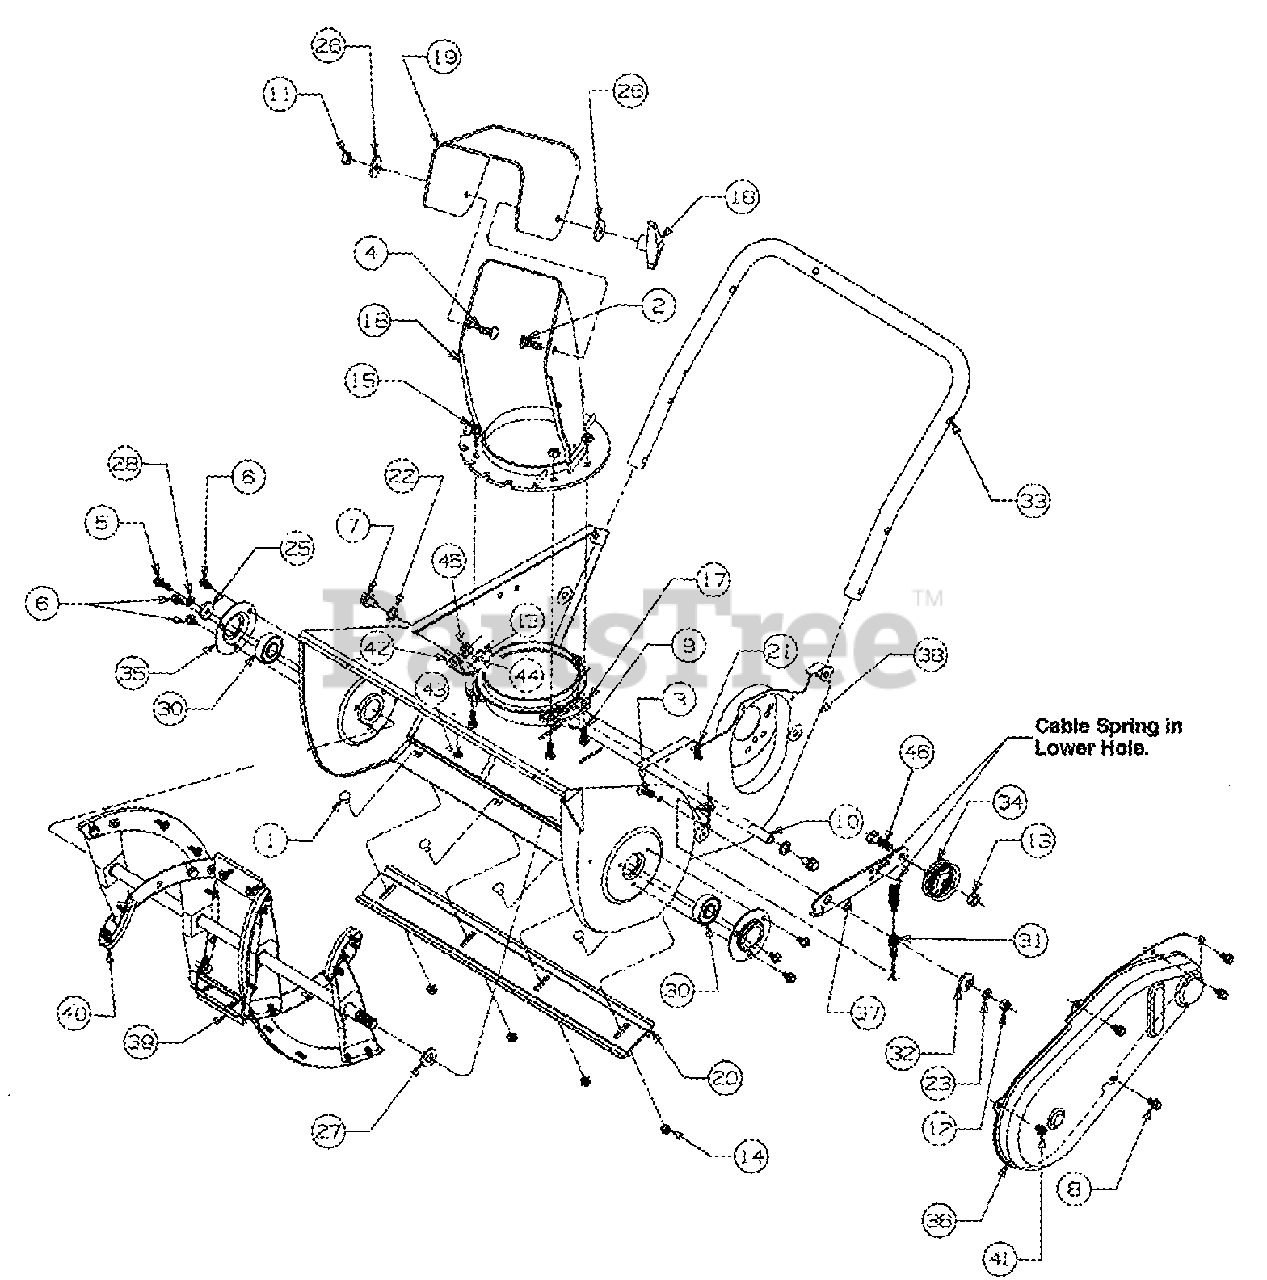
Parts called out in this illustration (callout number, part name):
1	Bolt - Carriage
2	Bolt - Carriage
3	Screw - Pan Head
4	Bolt - Carriage
5	Screw - Hex Washer
6	Screw - Hex Washer
7	Screw - Hex Washer
8	Screw - Hex Washer
9	Screw - Hex Cap
10	Axle
11	Nut - Hex Center Lock
12	Nut - Hex
13	Nut - Hex Lock
15	Nut - Hex Lock Flanged
17	Keeper - Chute
18	Chute - Lower
19	Chute - Upper
20	Shave Plate
21	Spring - Extension
22	Washer - Flat
23	Washer - Lock
25	Washer - Flat
27	Washer - Flat
28	Washer - Lock
30	Ball Bearing
31	Cable - Clutch
32	Spacer - Shoulder
39	Auger Ass'y. Comp.
40	Auger Rubber Replacement
41	Screw - Hex Washer
44	Washer - Bell
45	Bushing
46	Screw - Cap
